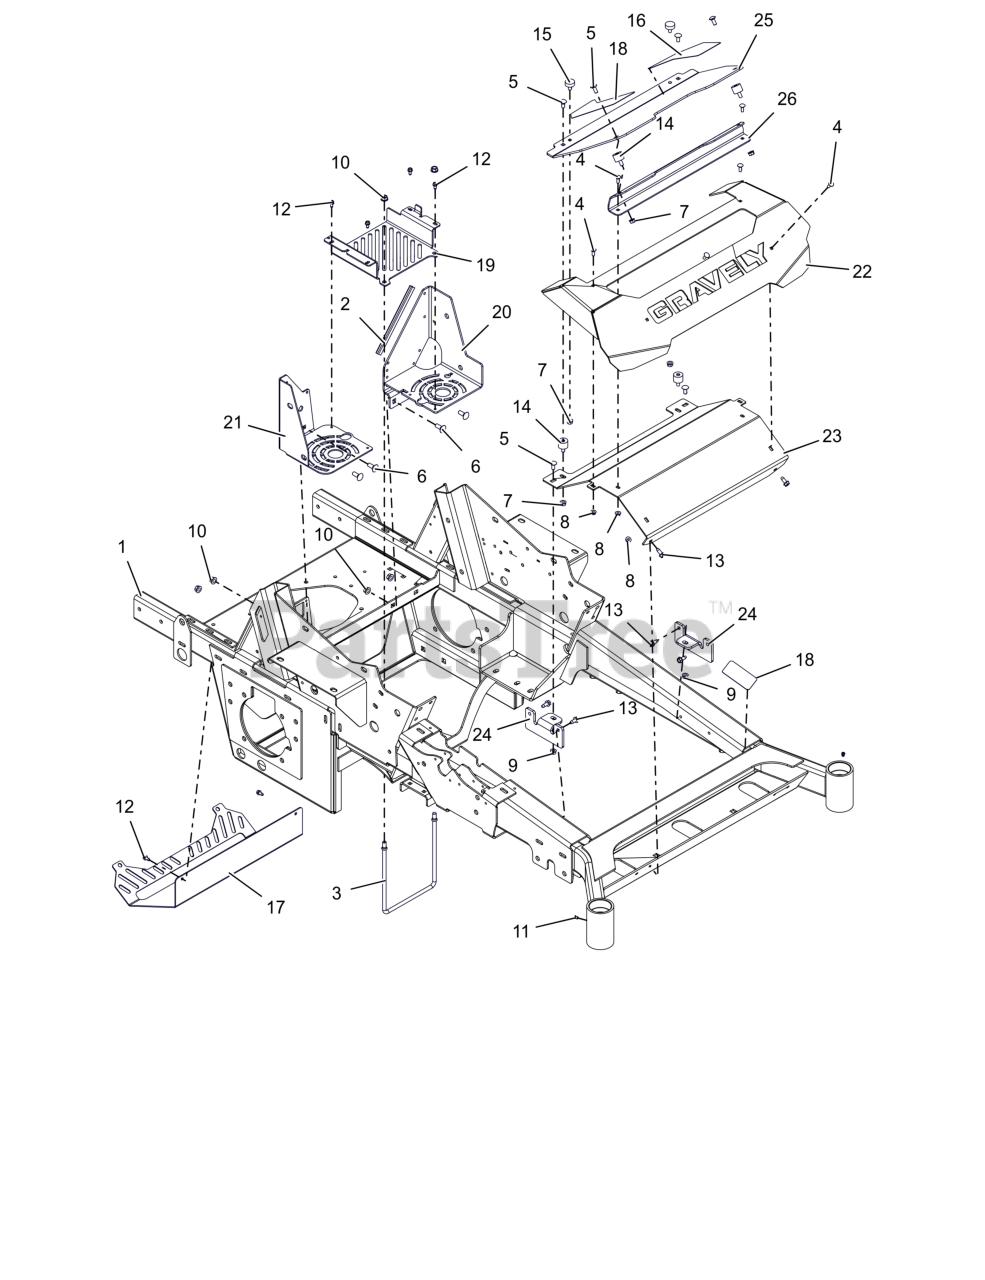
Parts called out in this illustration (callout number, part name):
1	WLDMT, 48", 52", 60" FRAME (RED)
2	STRIP, COWL
3	ROD, BRAKE MTG
4	BLT, RHSN .25-20X.750 G5 ZCC
5	BLT, RHSSN.31-18X.750 G5 ZCC
6	BLT, RHSN .38-16X1.00 G5 ZCC
7	NUT,SPNLK-FLG .31-18 G5 ZCC
8	NUT-LK-CTR-FLG .25-20 ZC120
9	NUT,LK-CTR-FLG .31-18 GF ZCC
10	NUT-LK-CTR-FLG .375-16 GF ZCC
11	FTG, .25-28 FLUSH MNT GREASE
12	SCR-TAP .25-20X.50 HWH ZCC
13	SCR,TAP .312-18X.75 HWH TR ZCC
14	BUMPER,STUD MNTD W/FEMALE INSR
15	BUMPER, RUBBER
16	KIT, PT300-600 ANTI-SKID Tape
17	GUARD, MUFFLER (BLACK)
18	KIT, PT300-600 ANTI-SKID Tape
19	TRAY- BATTERY
20	GUSSET-LH BATTERY TRY/ROPS-RED
21	GUSSET- FAN GUARD/ROPS - RED
22	BMPR-PT300-500 FRT FTRST/ -RED
23	BRKT-FRT BUMPER MTG/BACKER-BLK
24	BRKT- FOOTREST MTG
25	FOOTREST, PT300-500 (RED)
26	BRKT, FOOTREST SUPPORT (BLK)
